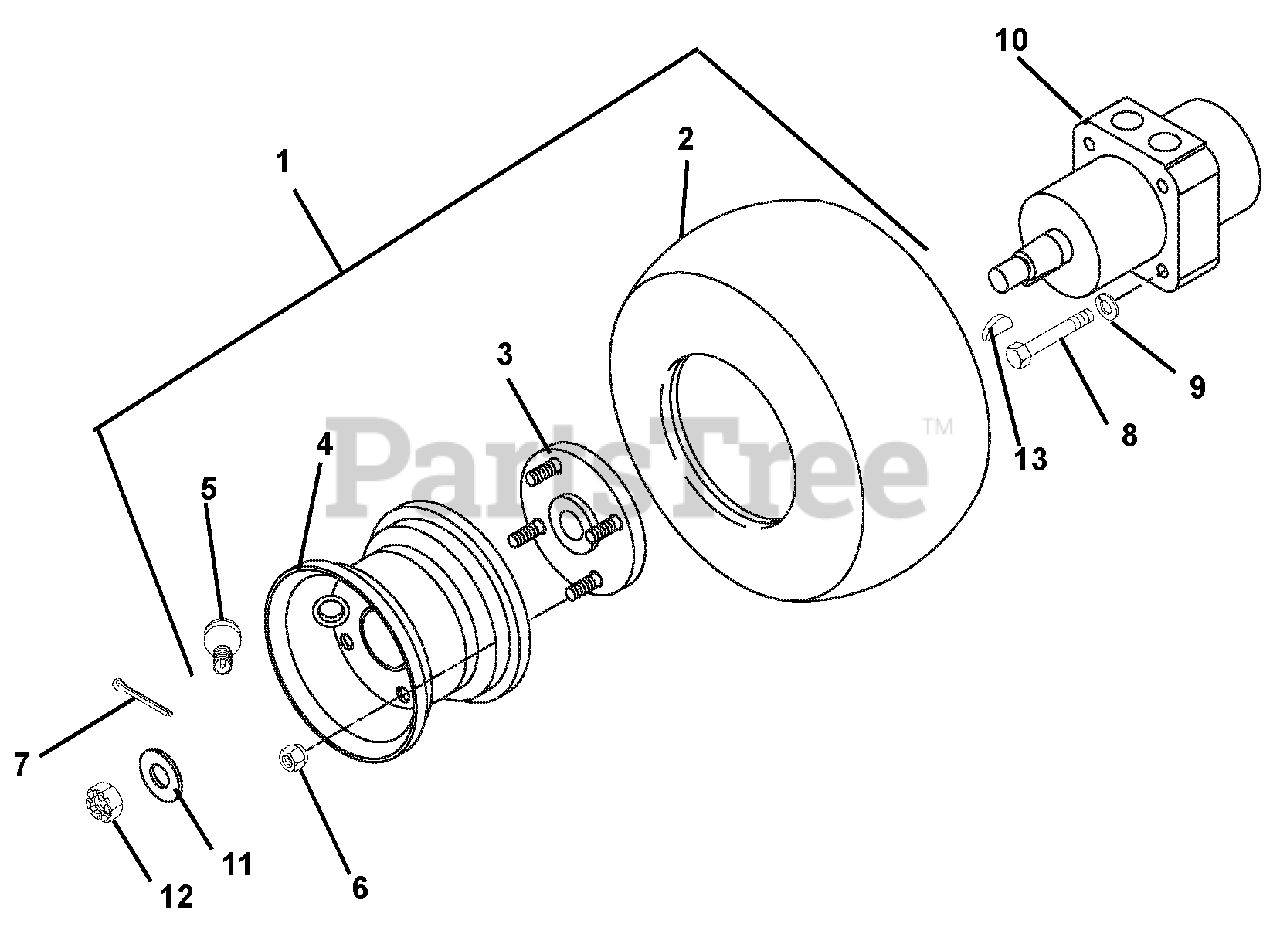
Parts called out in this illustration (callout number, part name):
1	Assembly, Tire and Wheel (includes 2 thru 6)
2	Tire 18 x 8.50 - 8
3	Assembly-Hub
4	Assembly-Rim
5	Valve Stem Assembly
6	Nut-Lug .50-20
7	Pin-Center .12 x 1.25
8	Bolt-Hex .38-16 x 1.00 Grade 5
9	Washer-Locking .38 x .094 Regular
10	Motor, Hydraulic Wheel
11	Washer-Flat-Steel .812 x 1.50 x .135
12	Nut, Hex .75-28 Slotted
13	Key-Woodruff .19 x .75
